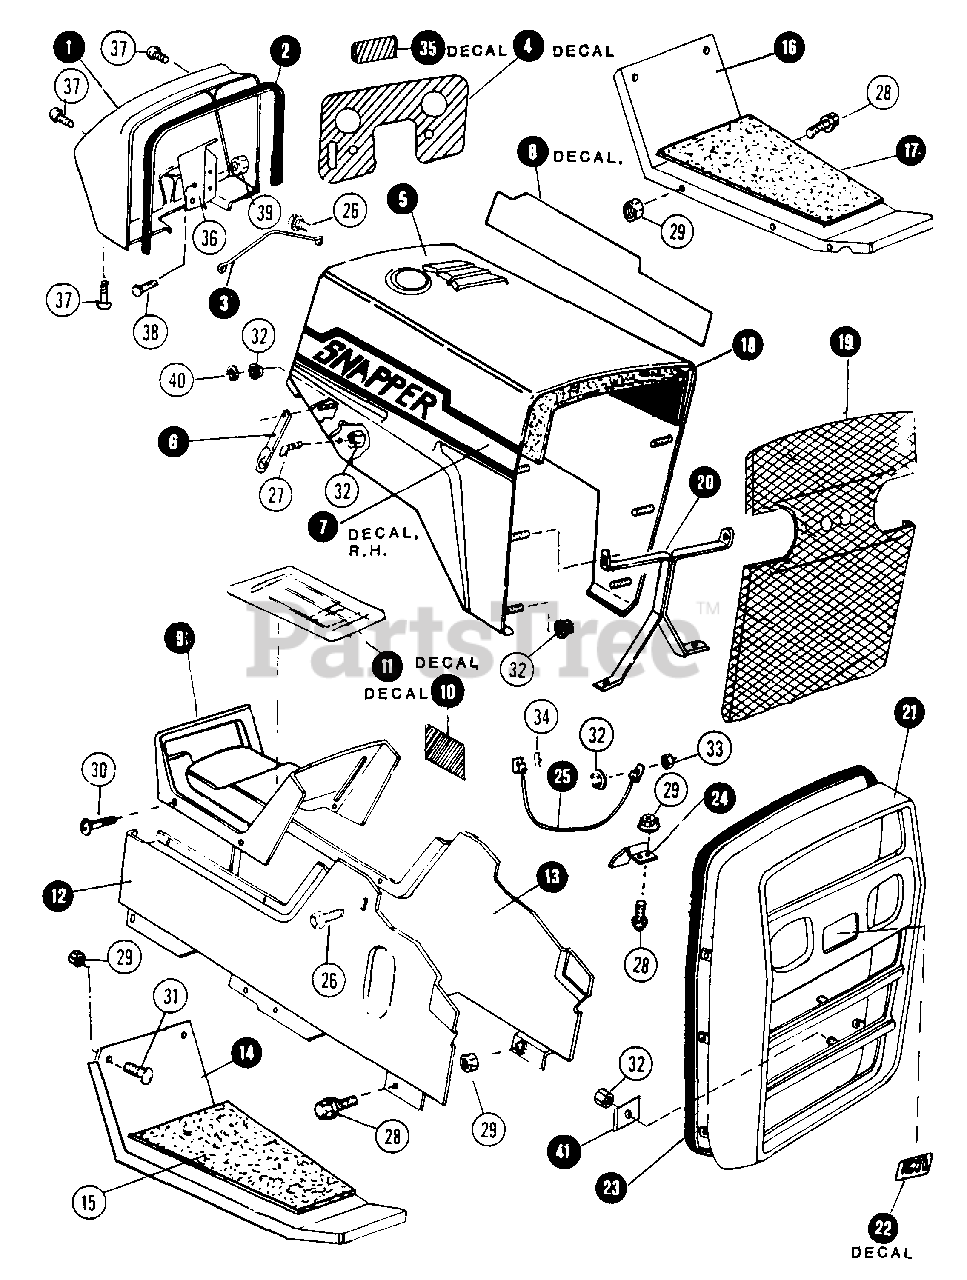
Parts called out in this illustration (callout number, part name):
1	COWL, INSTRUMENT DASH
2	TRIM, COWL MOLDING
3	REINFORCEMENT, COWL
4	DECAL, INSTRUMENT DASH
5	HOOD ASSEMBLY
6	STRAP, HOOD RETAINER
7	DECAL, SNAPPER RIGHT SIDE HOOD
8	DECAL SNAPPER LEFT SIDE HOOD
9	PANEL CENTER ACCESS CONSOLE
10	DECAL, CAUTION
11	DECAL, CONSOLE - OPERATING INSTRUCTION
12	PANEL, RIGHT SIDE
13	PANEL, LEFT SIDE
14	PLATE, RIGHT STEP
15	TREAD, RIGHT PLATE
16	PLATE, LEFT STEP
17	TREAD, LEFT STEP PLATE
18	INSULATION, HOOD - PANEL
19	GRILLE - SCREEN ASSEMBLY
20	BRACE, HOOD
21	GRILLE -PANEL ASSEMBLY
22	DECAL, 1600 SERIES IDENTIFICATION
23	TRIM, HOOD - GRILLE MOLDING
24	HINGE HOOD TILT
25	CABLE, HOLD TILT STOP
26	BOLT, 5/16F x 5/8 HEX FLANGE
27	LATCH, HOOD RETAINER STRAP
28	BOLT, 5/16C x 3/4 HEX FLANGE LOCK
29	NUT 5/16C HEX FLANGE LOCK
30	SCREW, PAN HEAD 5/16C x 1/2
31	SCREW, 5/16C x 5/8 ROUND HEAD
32	NUT, 1/4C HEX FLANGE LOCK
33	NUT, 1/4C HEX LOCK
34	PIN, HAIR
35	DECAL REFUEL CAUTION
36	BRACKET, COWL MOUNTING L.H.
37	SCREW, 5/16C x 3/4 ROUND HEAD
38	BOLT 3/8C x 3/4 HEX
39	NUT 3/8C HEX FLANGE LOCK
40	WASHER, 1/4 FLAT
41	WASHER, GRILLE SCREEN PLATE
